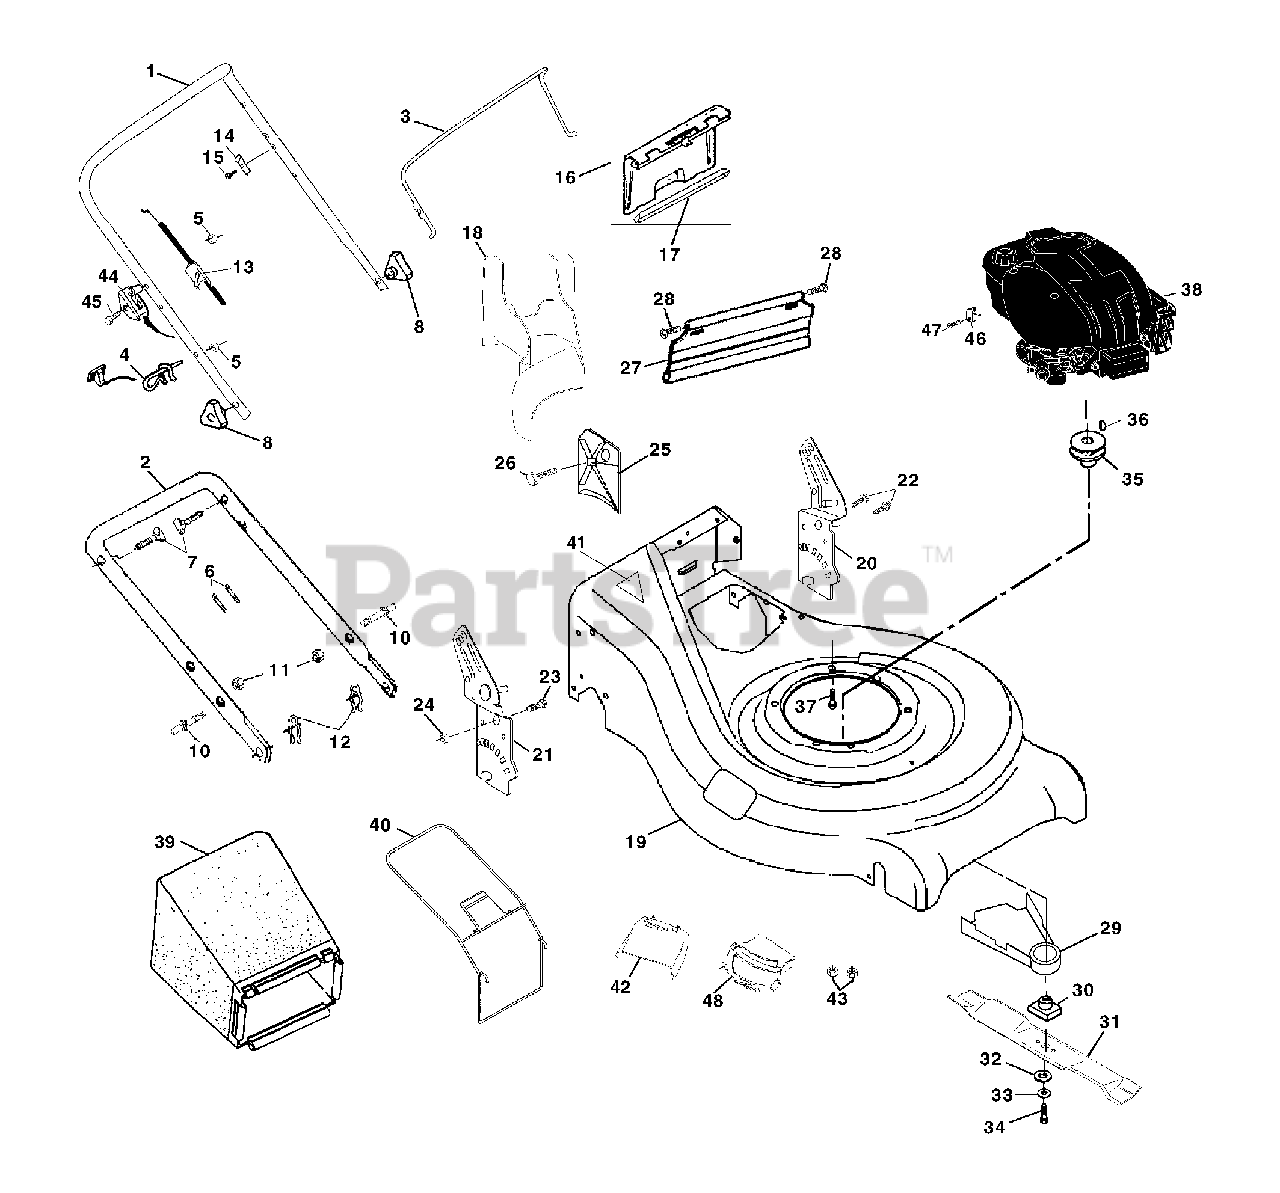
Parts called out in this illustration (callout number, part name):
1	Handle, Upper Dlx Comf.
2	Handle, Lower
3	Bail, Cont. Wire Dlx Comf. Blk
4	Guide, Rope, Side
5	Nut, Hex Lockwasher 1/4-20
6	Wire, Tie
7	Bolt, Handle 5/16-18 x 1.75
8	Knob, Handle
10	Bolt, Sq. Neck
11	Nut, Hex Lockwasher Ins. 5/16-18 UNC
12	Cotter, Hairpin
14	Bracket, Upstop
15	Screw, Hex Washer Head Tapping 10-2
16	Kit, Door Rear
17	Seal, Door
18	Plug, Mulcher
19	Kit, Housing
20	Handle, Bracket Asm. Left
21	Handle, Bracket Asm. Right
22	Screw, Hex Wshd
23	Bolt, Hex Head 5/16-18 x 5/8
24	Nut, Hex Lock Wshr 5/16-18
25	Baffle, Side
26	Screw 12 x 5/8
27	Skirt
28	Screw, Hinge 1/4-20 x 1.25
29	Shield, Debris Modified
30	Adapter, Blade w/key Longer
31	Blade, 21"
32	Washer, Hardened
33	Lockwasher, Helical Spring 3/8
34	Screw, Hex Head 3/8-24 x 1.38
35	Pulley, Engine
36	Key, Hi Pro
37	Bolt, Engine
38	Engine Briggs & Stratton
39	Grass Catcher Bag
40	Grass Catcher Frame
41	Danger Decal
42	Deflector
43	Nut
44	Throttle Control
45	Screw
46	Cable Clamp
48	Mulcher Door
